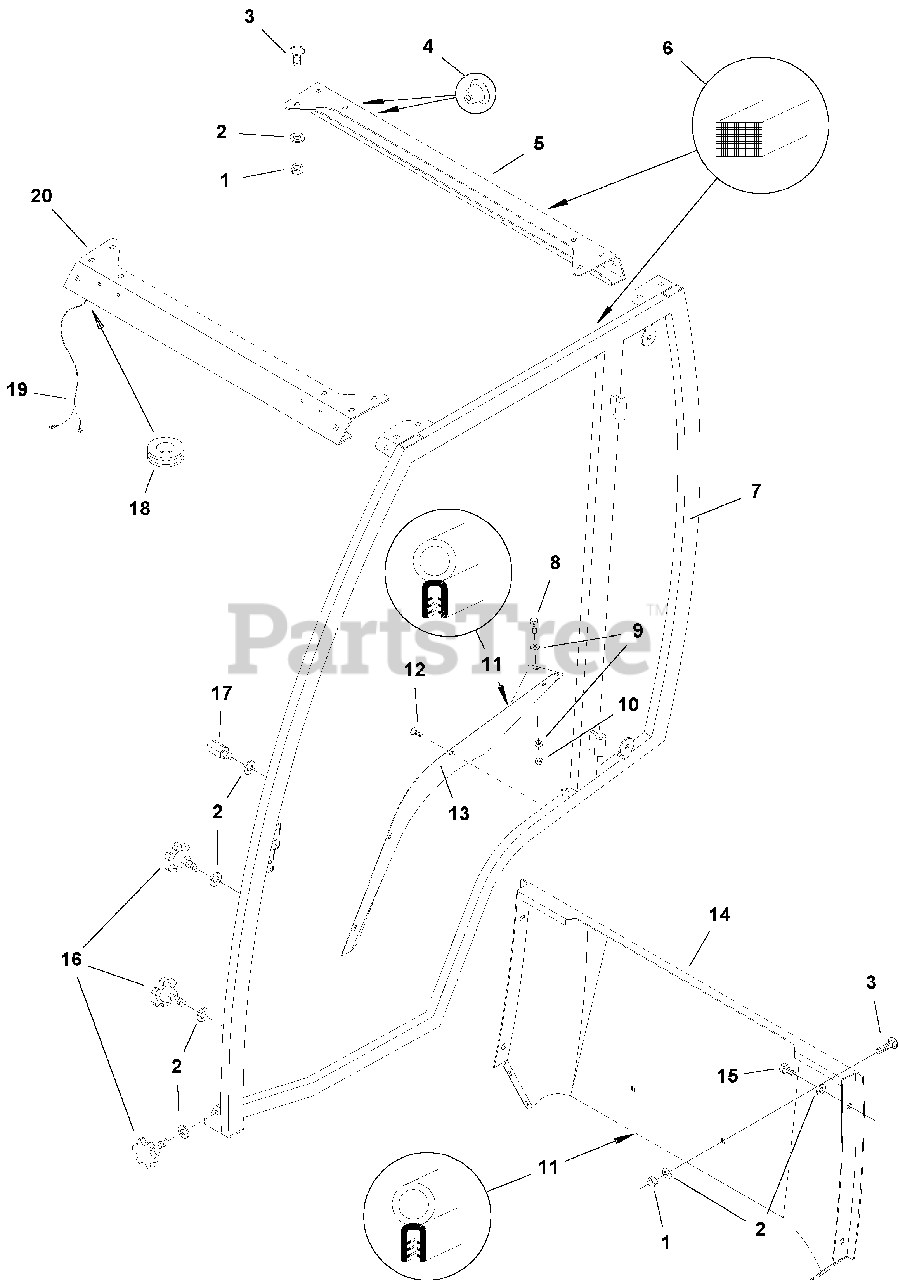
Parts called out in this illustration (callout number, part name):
4	GROMET, D=7
5	CROSS MEMBER, Upper Rear
6	COMPRIBAND, A 20/15, 10 ft.
7	SIDEFRAME, Left
7	SIDEFRAME, Right
11	PROFILE SEALING, 10 ft.
12	TAPPING SCREW, 4.8 x 16
13	FENDERSHIELD, Left
13	FENDERSHIELD, Right
14	REAR SHIELD
16	GRIP SCREW, 40/8 x 20
17	GASLIFT SOCKET
18	CABLE GUIDE, 12MM
19	WIRING, Complete
20	CROSS MEMBER, Upper Front
